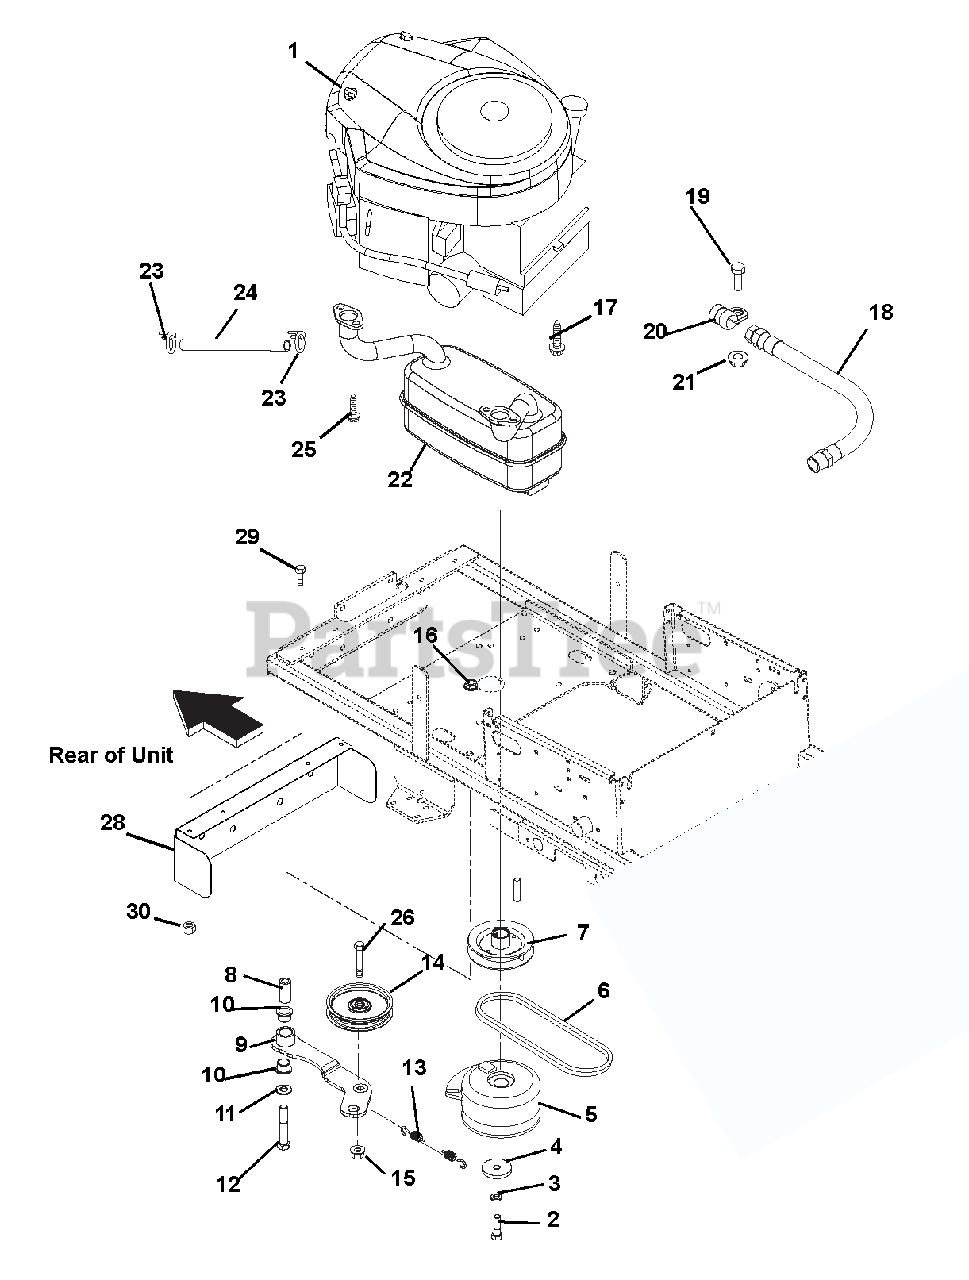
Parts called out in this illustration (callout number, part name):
1	ENGINE, 16HP V-TWIN CE
2	7/16-20X3 HHCS GR8 YWZC
3	@WSHR-LK .44X.109 REG YWZC
4	WSHR-FL-STL .469X2.00X.25 YWZC
5	RMS CLUTCH, ELECTRIC
6	V-BELT, HA-WRAPPED
7	PLY-V 3.75X1.0 A SECTION W/KEY
8	BSHG-SLV .500X.750X1.560
9	WMT, IDLER
10	BSHG-FLG 0.75X0.875X.625X1.125
11	@WSHR-FL-STL.531X1.06X.095YWZC
12	@BLT-HEX .50-13X3.25 GR5 YWZC
13	SPRING, EXT
14	ASM, 4" IDLER (.75 WIDE)
15	@NUT-LK-NYL-FLG .38-16 YWZC
16	@NUT-LK-TOP-FLG .50-13 YWZC
17	@SCR-TAP .38-16X1.00 HWH TR YZ
18	HOSE, HYD .38-11-0K M6N0-F6J0
19	@BLT-HEX .31-18X.75 GR5 YWZC
20	CLAMP, CUSHIONED STEEL .75
21	@NUT-LK-NYL-FLG .31-18 YWZC
22	MUFFLER - TWIN BRIGGS
23	CLAMP-HOSE WIRE .490/.510X.116
24	HOSE, .25 LOW-PERM BULK GAS
25	SCR-CAP .31-18X.75 S/HD
26	@BLT-HEX .38-16X2.00 GR5 YWZC
27	KEY-SQ .25X1.0X.25 SAE 8630
28	GUARD, MUFFLER
29	@BLT-HEX .25-20X.75 GR5 YWZC
30	@NUT-LK-TOP-FLG .25-20 YWZC
